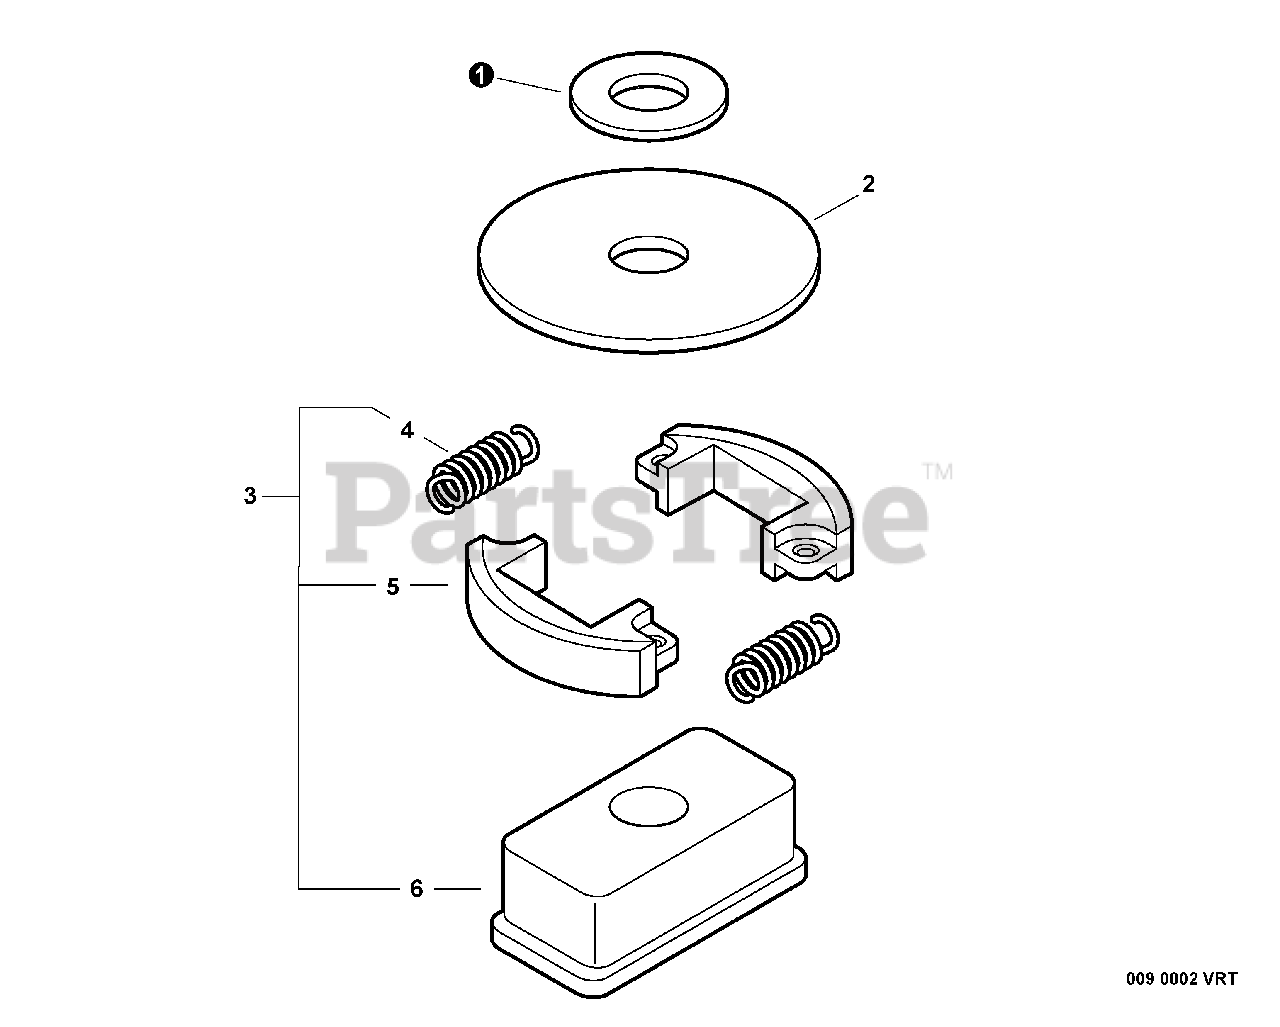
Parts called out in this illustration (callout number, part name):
1	WASHER, CLUTCH
2	PLATE, CLUTCH
3	CLUTCH ASSY
4	SPRING, CLUTCH
5	SHOE, CLUTCH
6	HUB, CLUTCH
